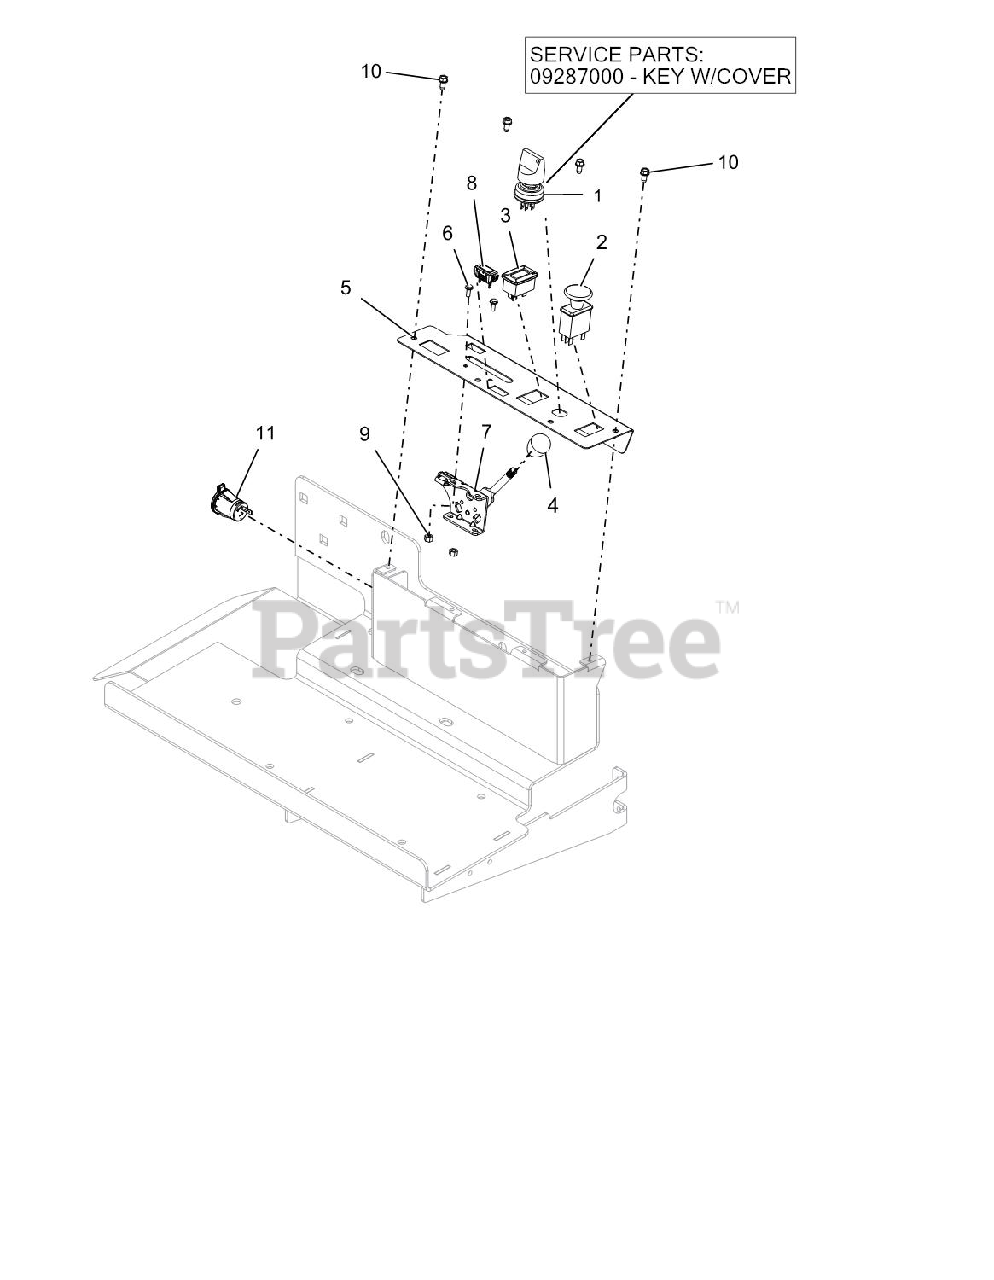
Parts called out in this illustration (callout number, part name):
1	SWITCH, IGNITION
1	KEY W/COVER
2	SWITCH, CLUTCH
3	METER, HOUR W/MAINTENANCE
4	KNOB, CONTROL BLACK .38-16X.50
5	PANEL, CONTROL PT400 - LP
6	SCR-MCH 10-24X.5 HWH YWZC
7	CABLE, PRO-CONTROL THROTTLE
8	LIGHT, INDICATOR
9	NUT-LK-NYL #10-24 YWZC
10	SCR-TAP .25-20X.50 HWH TR YWZ
11	PORT, 12 VOLT POWER
